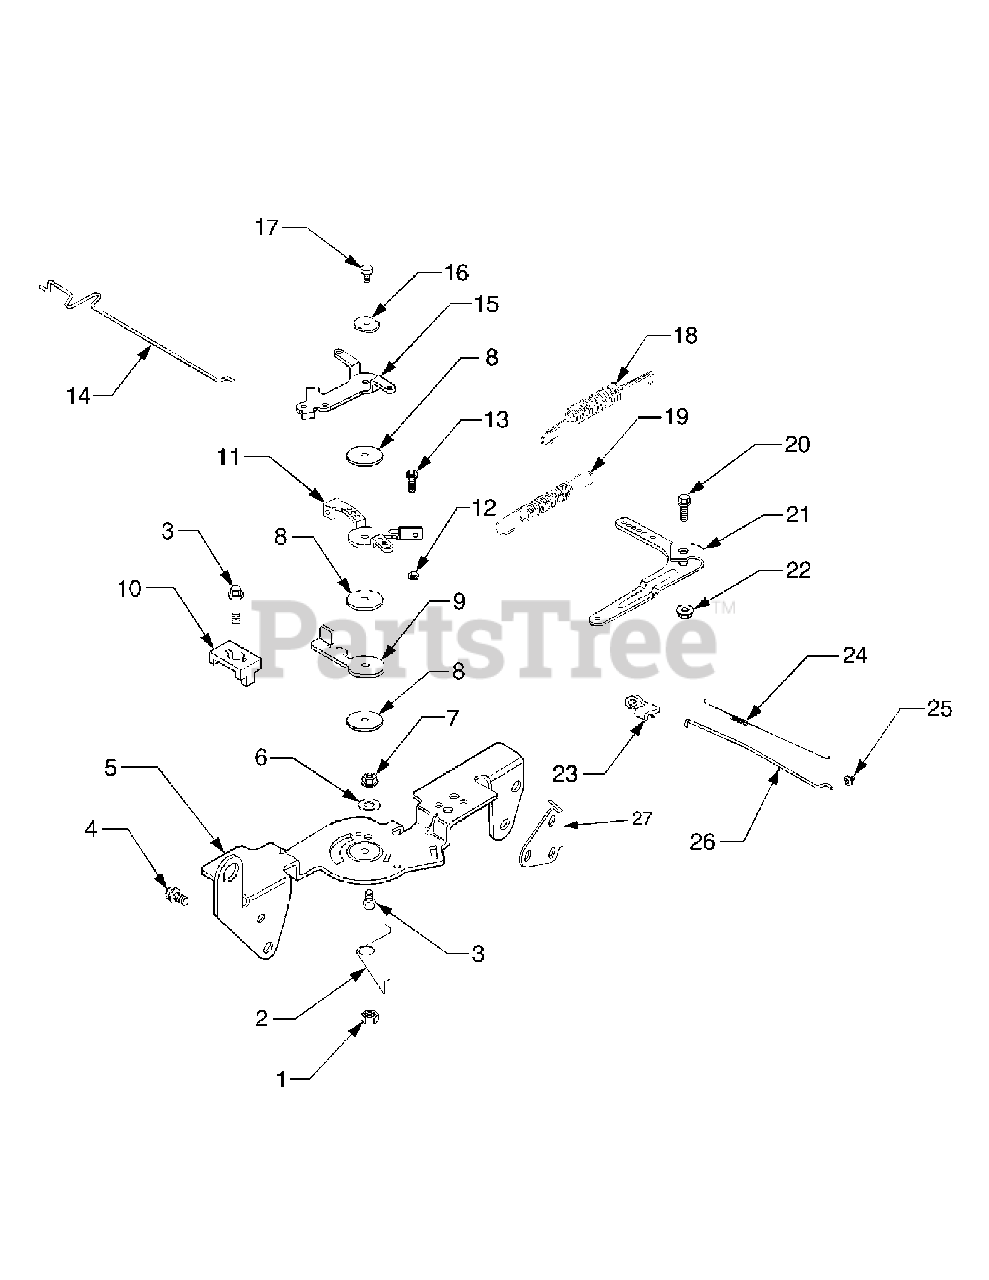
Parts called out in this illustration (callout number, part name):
1	Nut, Hex Lock M5 x 0.8
2	Spring, Choke Return
3	Screw, Hex Flange M5 x 0.8 x 16
4	Screw, Hex Flange M6 x 1.0 x 16
5	Bracket, Control
6	Washer, Lock
7	Nut, Hex Flange
8	Washer, Plain 5.5mm
9	Lever, Throttle Actuator
10	Clamp, Cable
11	Lever, Throttle Control
12	Nut,H ex M4 x 0.7
13	Screw, Hex Cap M4 x 0.7 x30
14	Linkage, Choke
15	Lever, Choke
16	Washer, Spring 1/4"
17	Screw, Hex Flange M5 x 0,.8 x 20
18	Spring, Throttle Limiter
19	Spring, Governor
20	Screw, Round Hd. Square Neck
21	Lever, Governor
22	Nut, Hex Flange M6 x 1.0
23	Bushing, Linkage Retaining
24	Spring, Linkage
25	Bushing, Linkage Retaining
26	Linkage, Throttle
27	Bracket
